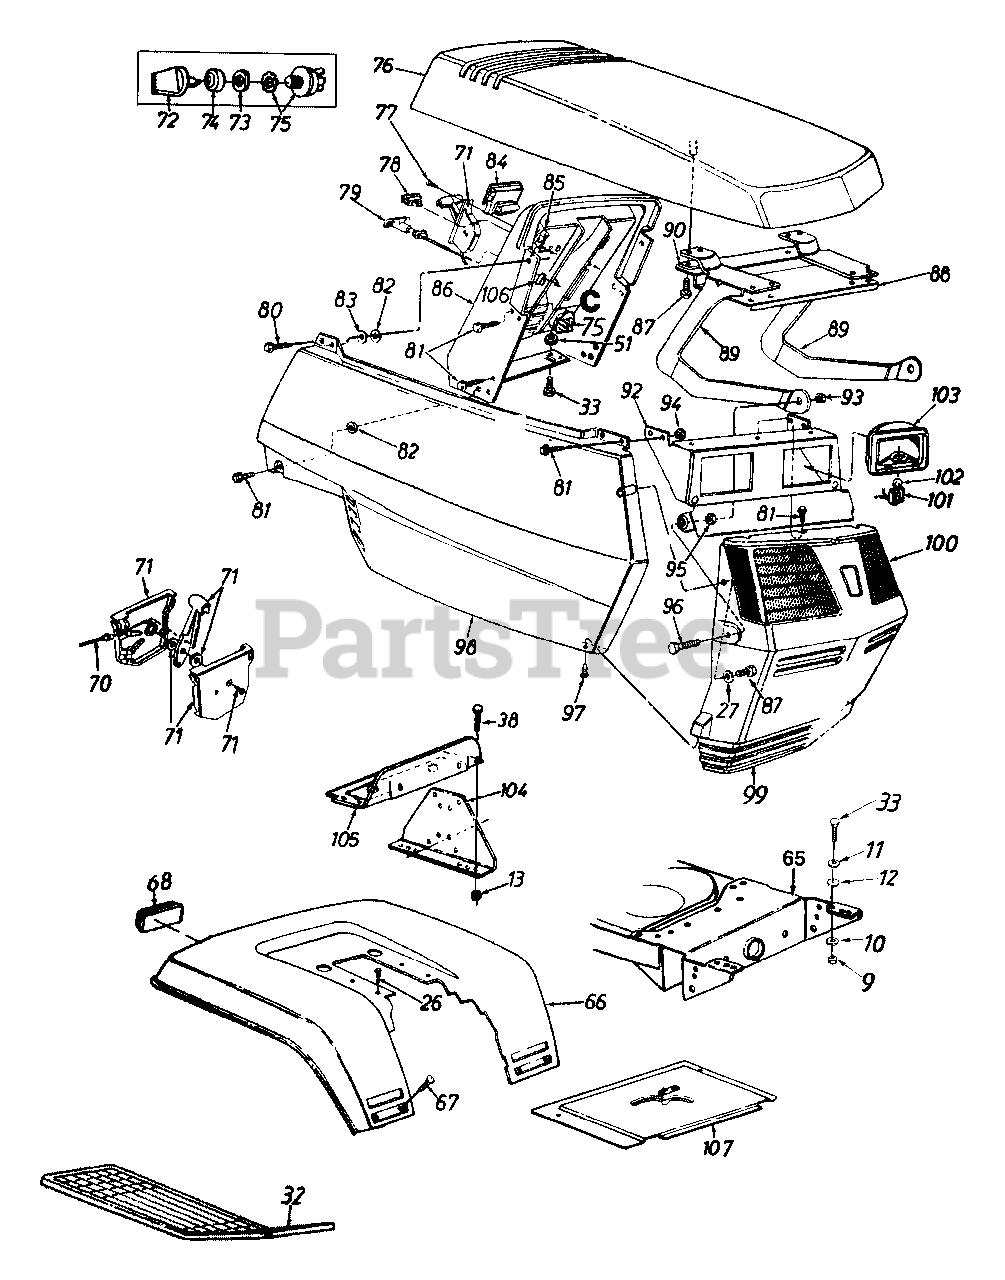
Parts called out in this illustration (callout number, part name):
9	Hex Nut 5/16-18 Thd.
10	L-Wash. 5/16" I.D.
11	Fl-Wash. .34" I.D. x 1" O.D.
12	Speed Nut
13	Hex Sems Nut 1/4-20 Thd.
26	Hex Wash. Hd. AB-Tap Scr. 5/16 x .75"
27	Fl-Wash. .218" I.D. x .5" O.D.
32	Rubber Foot Pad L.H.
33	Hex Bolt 5/16-18 x .75" Lg.
38	Hex Bolt 1/4-20 x .62" Lg.
51	Hex Sems Nut 5/16-16 Thd.
68	Reflector
70	Throttle Wire 18.5" Lg.
71	Throttle Control Box Ass'y.
72	Ignition Key
73	Ignition Switch Nut
74	Ignition Switch Cap
75	Ignition Switch
76	Hood-Yellow
77	Truss Mach. AB-Tap Scr. #10 x .5" Lg.
78	Light Switch
79	Choke Control 29" Lg.
80	Hex Wash. Hd. Tap Scr. 1/4 x .75"
81	Hex Tap Scr. 1/4-20 x .5" Lg.
82	Push Nut Fastener
83	Fl-Wash. .27" I.D. x .948"
84	Ammeter
85	Speed Nut 1/4-20 Thd.
86	Dash Panel
87	Hex Wash. Hd. B-Tap Scr. 1/4 x .75"
94	Hex L-Nut 1/4-20 Thd.
95	Hex Jam Nut 5/16-18 Thd.
96	Hex Bolt 5/16-18 x 7/8" Lg.
97	Truss Mach. B-Tap Scr. #10 x .5" Lg.
98	Side Cover-RH Yellow
99	Grille-Yellow
100	Lens-L.H.
101	Twist Lock - Lamp Socket
102	Lamp
103	Headlight Housing
